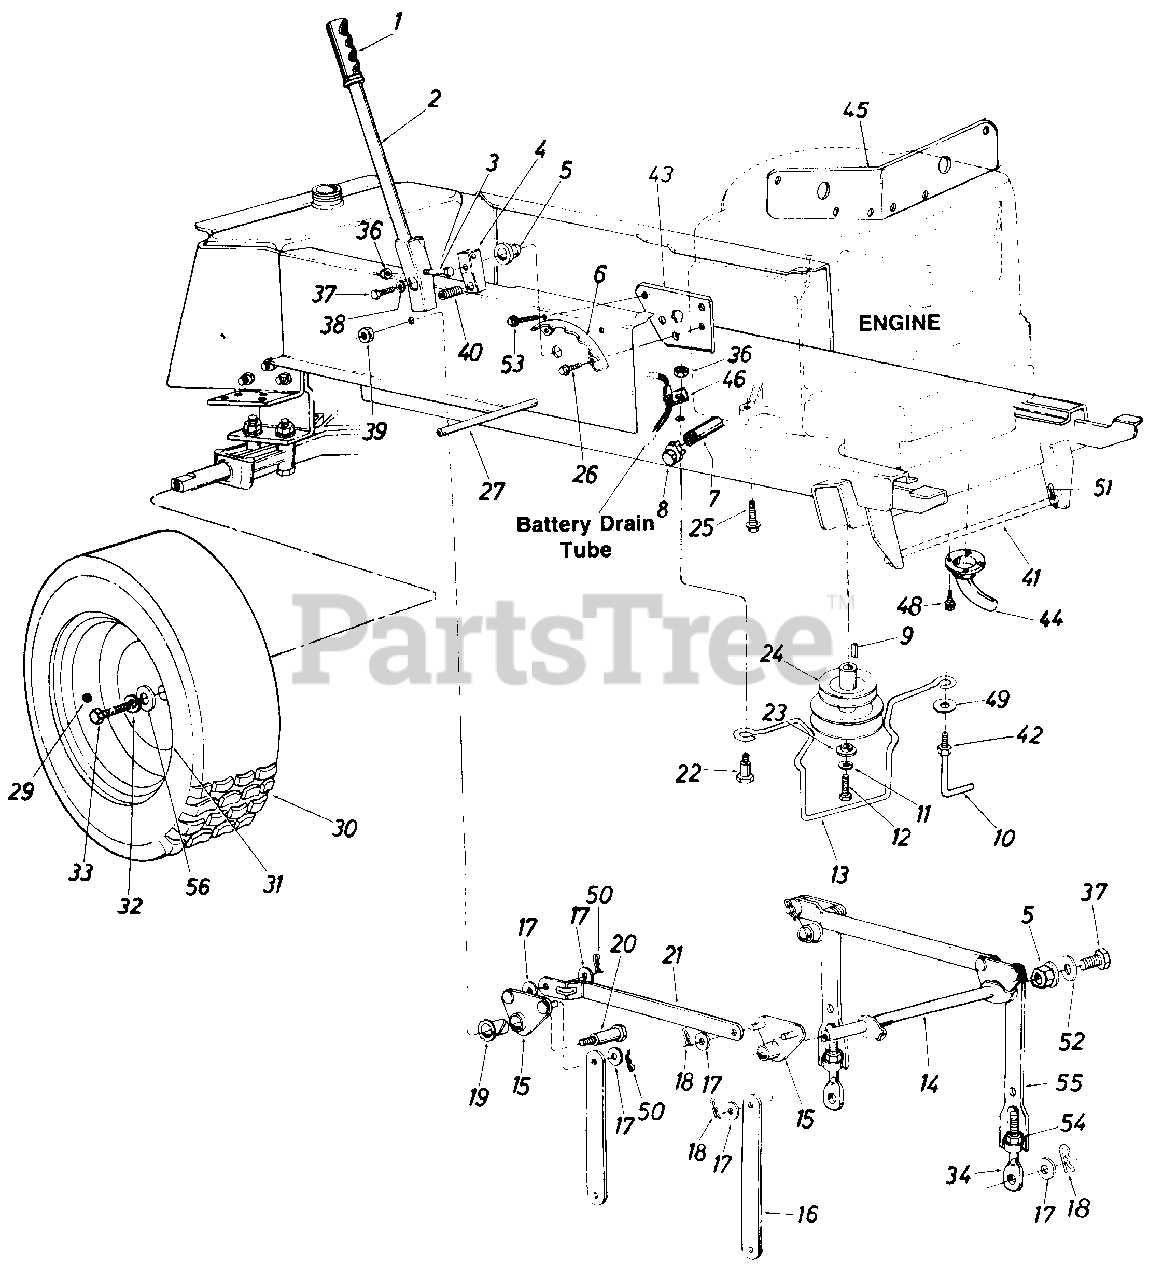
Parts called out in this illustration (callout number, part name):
1	Grip
2	Lift Handle Ass'y.
3	Hex Scr. 5/16-18 x 1.50" Lg.
4	Lift Shaft Drive
5	Plastic Hex Brg. 5/8" I.D.
8	Pipe Cap 3/8-18 Npt.
9	Sq. Key 1/4" x 1.50" Lg.
10	Belt Guard Lock Pin
11	'L-Wash. 7/16" Scr.
12	Hex Scr. 7/16-20 x 1.50" Lg.
13	Belt Guard
14	Lift Shaft Ass'y.
15	Lift Pivot Brkt. Ass'y.
17	Fl-Wash. 1/2" I.D. x 1.00" O.D. x .090
18	Hairpin Cotter
19	Nyliner 5/8" I.D. x .88" Lg.
20	Shld. Scr. 5/8" Dia. x .96" Lg. 3/8-16
23	Flat Wash. .44" I.D. x 1.25" O.D. x .17
24	Two-Step Engine Pulley
25	Hex Wash. Hd. Scr. 3/8-16 x 1.25" Lg.
26	Hex Thd. Rolling Scr. 5/16-24 x .50" Lg.
27	Running Board Rod
29	Air Valve
30	Rear Wheel Ass'y. Comp.
31	Rear Wheel Rim Only
32	Bell-Wash. .345" I.D. x .88" O.D.
33	Hex Bolt 5/16-24 x .75" Lg.
34	Eye Bolt Adj. Link 1/2-13 Thd.
36	Hex Cent. L-Nut 5/16-18 Thd.
37	Hex Scr. 5/16-24 x .62" Lg.
38	L-Wash. 5/16" I.D.
39	Hex Center L-Jam Nut 3/8-16 Thd.
40	Compression pring
41	Deck Connecting Rod
42	Hex Nut 5/16-24 Thd.
45	Heat Shield
46	Mounting Clamp
48	Hex Wash. Hd. AB-Tap Scr. #10 x .50" Lg.
49	Bell-Wash. .39" I.D.
50	Cotter Pin .09 Dia. x 1.0" Lg.
51	Int. Cotter Pin
52	Flat Wash. .34" I.D. x 1.12" O.D. x .125
53	Hex Wash. Hd. AB-Tap Scr. 5/16 x .62" Lg.
54	Hex Nut 1/2-13 Thd .
55	Adj. Deck Link
56	Fl-Wash. .34" I.D. x 2.0" O.D.
